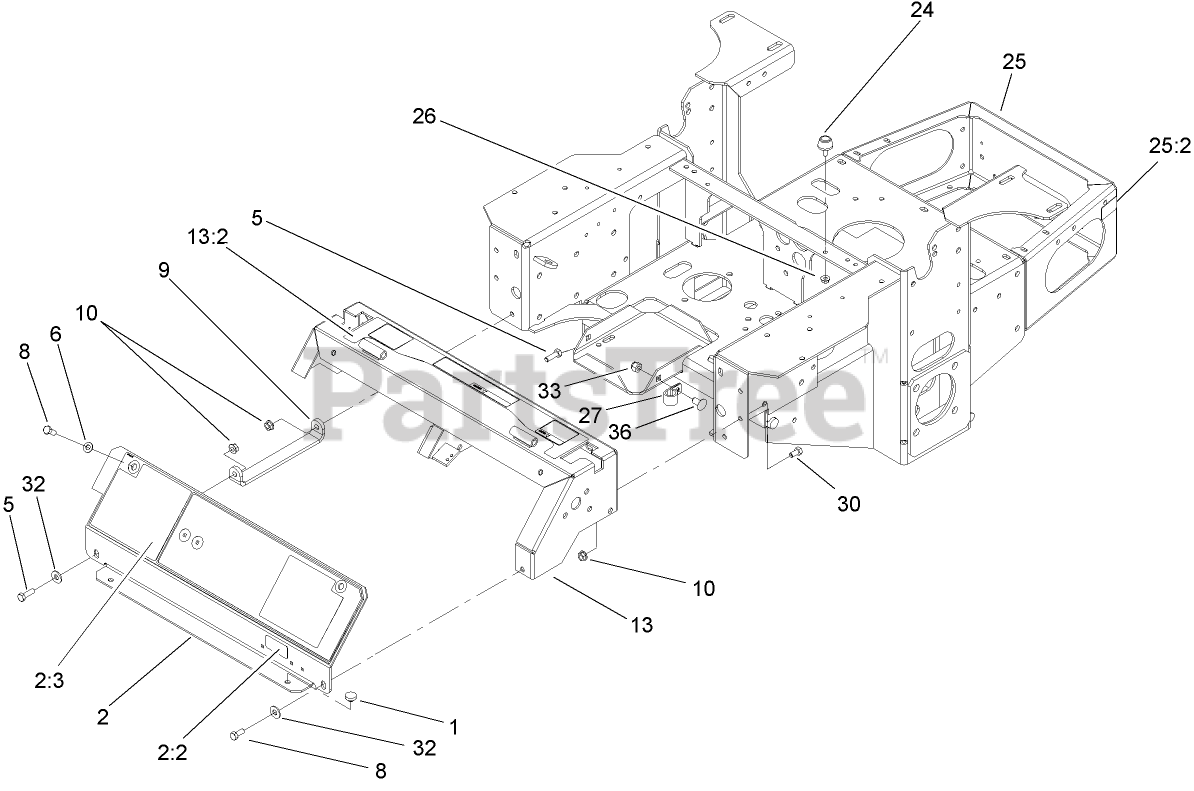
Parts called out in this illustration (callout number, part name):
1	BUMPER
2	PANEL ASM
2:2	DECAL-PROTECTION, EAR
2:3	DECAL-COVER, PANEL
5	SCREW-HH
6	WASHER-PLAIN
8	SCREW-HH
9	BRACKET
10	NUT-HF
13	CONSOLE ASM
13:2	DECAL-WARNING
24	BUMPER
25	MAIN FRAME ASM
25:2	DECAL-SURFACE, HOT
26	NUT-HF
27	CLIP-LOOM
30	SCREW-HH
32	WASHER-FLAT
33	NUT-LOCK, NI
36	SCREW-CARR
